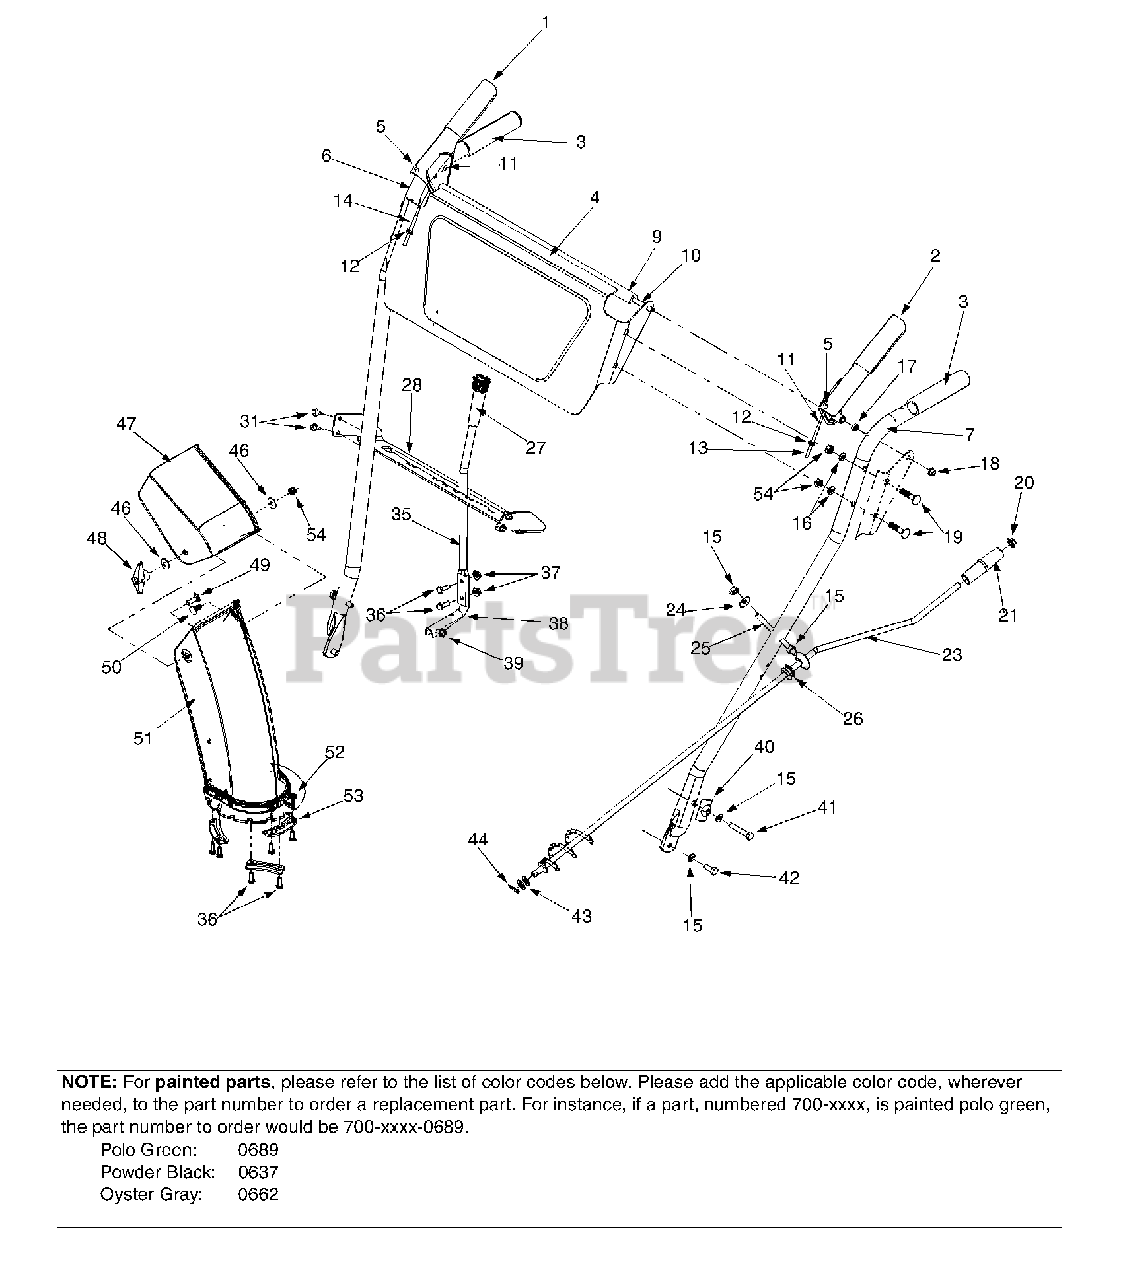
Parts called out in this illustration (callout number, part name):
1	Clutch Lever Assembly - RH
2	Clutch Lever Assembly - LH
10	Pivot Rod
11	"Z" Fitting
12	Hex Nut
13	Auger Clutch Cable
14	Drive Clutch Cable
15	Hex Nut 5/16-18
16	Lock Washer 5/16
17	Spacer
18	Push Cap
19	Carriage Bolt 5/16-18 x 1.5
20	Push Cap
21	Chute Crank Knob
23	Chute Crank Assembly
24	Bell Washer .340 ID x .873 OD
25	Eyebolt
26	Rubber Grommet
31	Hex Wash. Screw 1/4-20 x .50
36	Hex Cap Screw 1/4-20 x .75
37	Hex Lock Nut 1/4-20
38	Shift Lever Support
39	TT Screw
40	Handle Tab
41	Hex Cap Screw 5/16-18 x 1.75
42	Hex Cap Screw 5/16-18 x .75
43	Flat Washer 3/8 ID x .738 OD
44	Cotter Pin
46	Washer 5/16
47	Upper Chute
48	Wing Knob 5/16-18
49	Carriage Screw 5/16-18 x 1.0
50	Carriage Bolt 5/16-18 x .75
51	Lower Chute
52	Hex Lock Nut 1/4-20
53	Chute Flange Keeper
54	Hex Lock Nut 5/16-18
